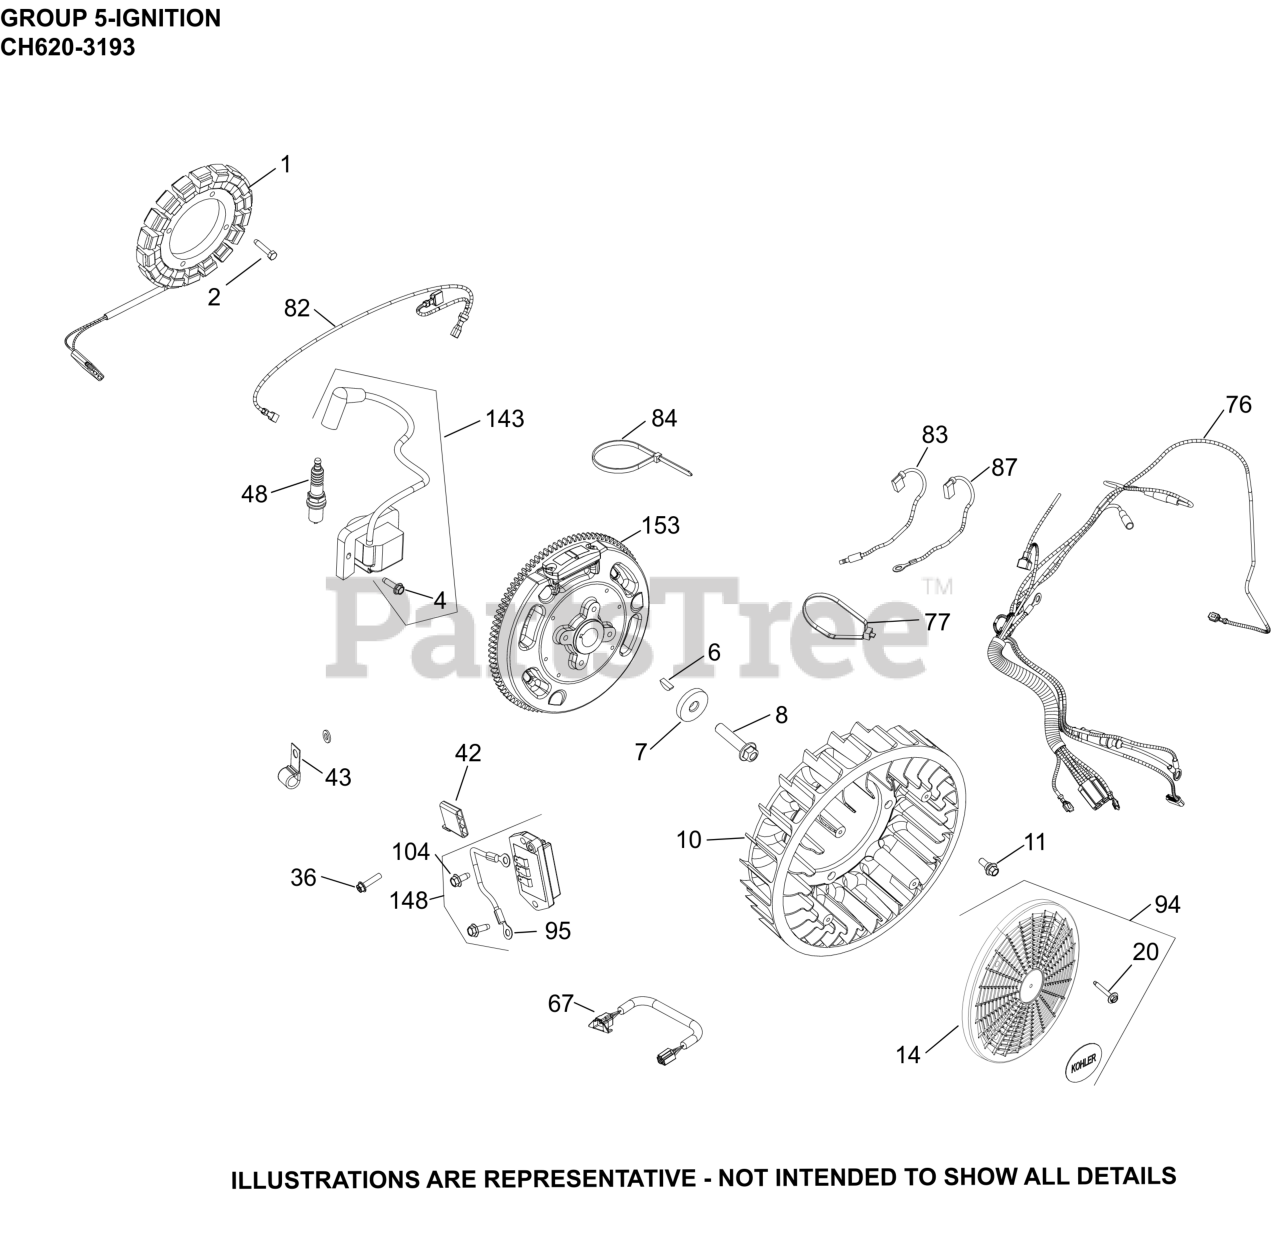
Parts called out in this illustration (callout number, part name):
1	KIT, 15 / 20 AMP STATOR
2	SCREW, THREAD FORMING
4	SCREW, THREAD FORMING
6	KEY, 3/16" X 5/8"
7	WASHER, FLAT
8	SCREW, HEX FLANGE
10	FAN-USE 24 755 253-S
11	BOLT, SHOULDER
14	SCREEN, GRASS
20	SCREW, FLG SEMS M4x.7x25
36	SCREW, HEX FLANGE HI-LO
42	CONNECTOR
43	CLIP, CABLE
48	PLUG, SPARK (STD)
67	CONNECTOR
76	HARNESS WIRING ASSEMBLY
82	LEAD, DUPLEX
83	LEAD, OIL SENTRY
87	LEAD, 20/25 AMP B+
94	KIT GRASS SCREEN
104	SCREW, THREAD FORMING
143	KIT IGNITION MODULE
148	KIT, REGULATOR RECT (12/15 AMP)
153	FLYWHEEL ASSEMBLY (LW, 22)
